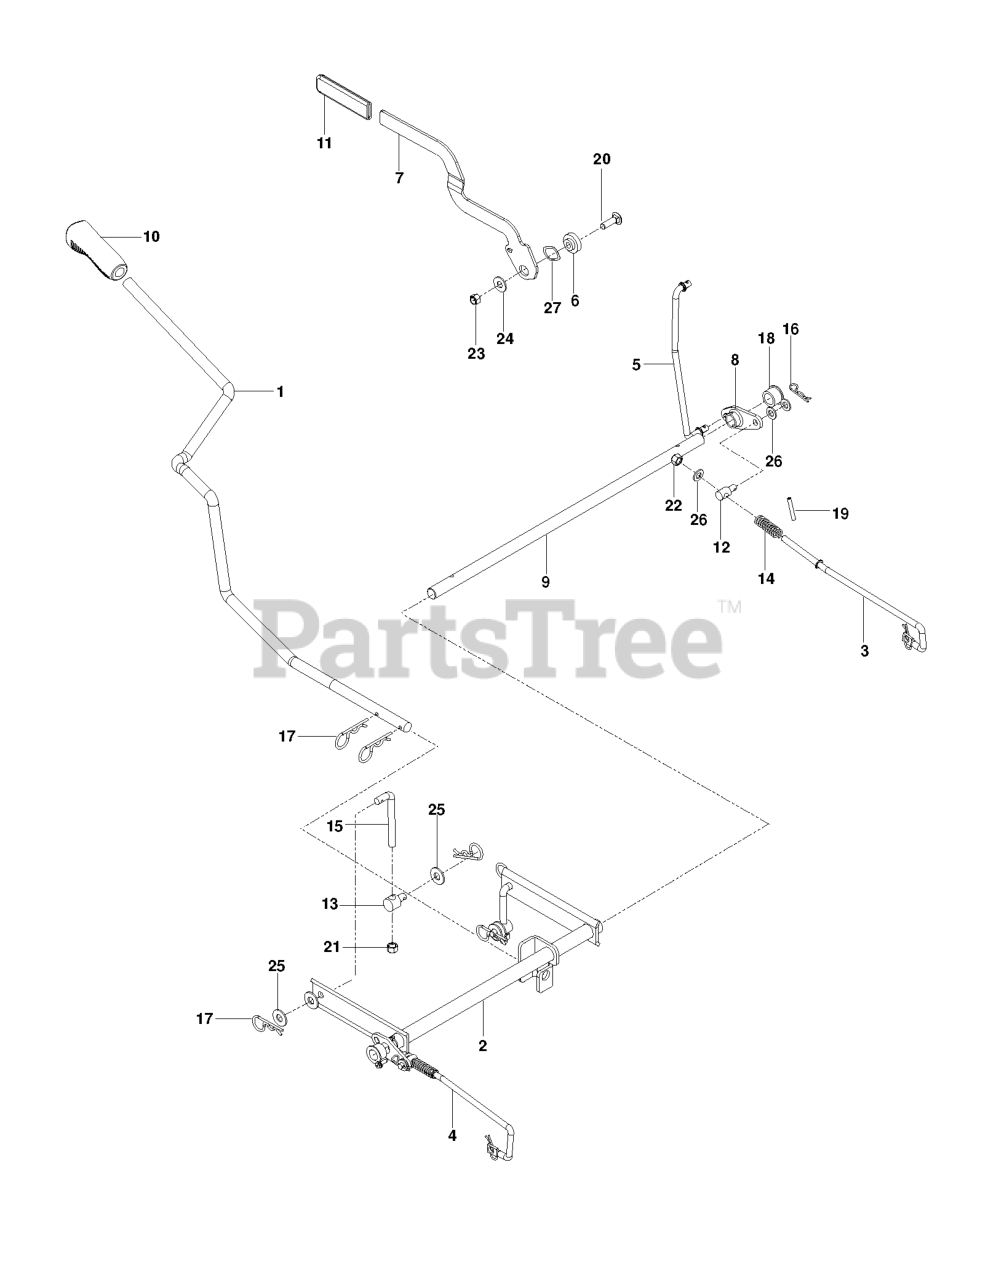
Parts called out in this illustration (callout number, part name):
1	ARM, LIFT HANDLE, BLK
2	SHAFT, LIFT WLDMT, BLACK
3	LINKAGE, EZT BRAKE RT
4	LINKAGE, EZT BRAKE LT
5	LINKAGE, BRAKE, UPPER
6	BRAKE ARM PIVOT
7	HANDLE, BRAKE, BLK
8	BELLCRANK, BRAKE
9	ROD, BRAKE
10	GRIP.LEVER.5625.ID
11	GRIP BRAKE HANDLE
12	BRAKE SWIVEL
15	L ROD 3-1/8"
16	HAIRPIN #2
17	HAIRPIN #4
18	PLASTIC BUSHING
19	ROLL PIN 3/16 X 1-1/4 ZD
20	RHSNB 3/8-16 X 1-1/4
21	NUT 3/8-16 NYLOC
22	NUT 5/16 NYLOC
23	NUT HEX 3/8-16 NYLON, THIN
24	WASHER, 7/16 DISC SPRING
25	RP WASHER 3/8 FLAT
26	FLAT WASHER 5/16 SAE
27	WASHER, .825 X 1.087, WAVE
